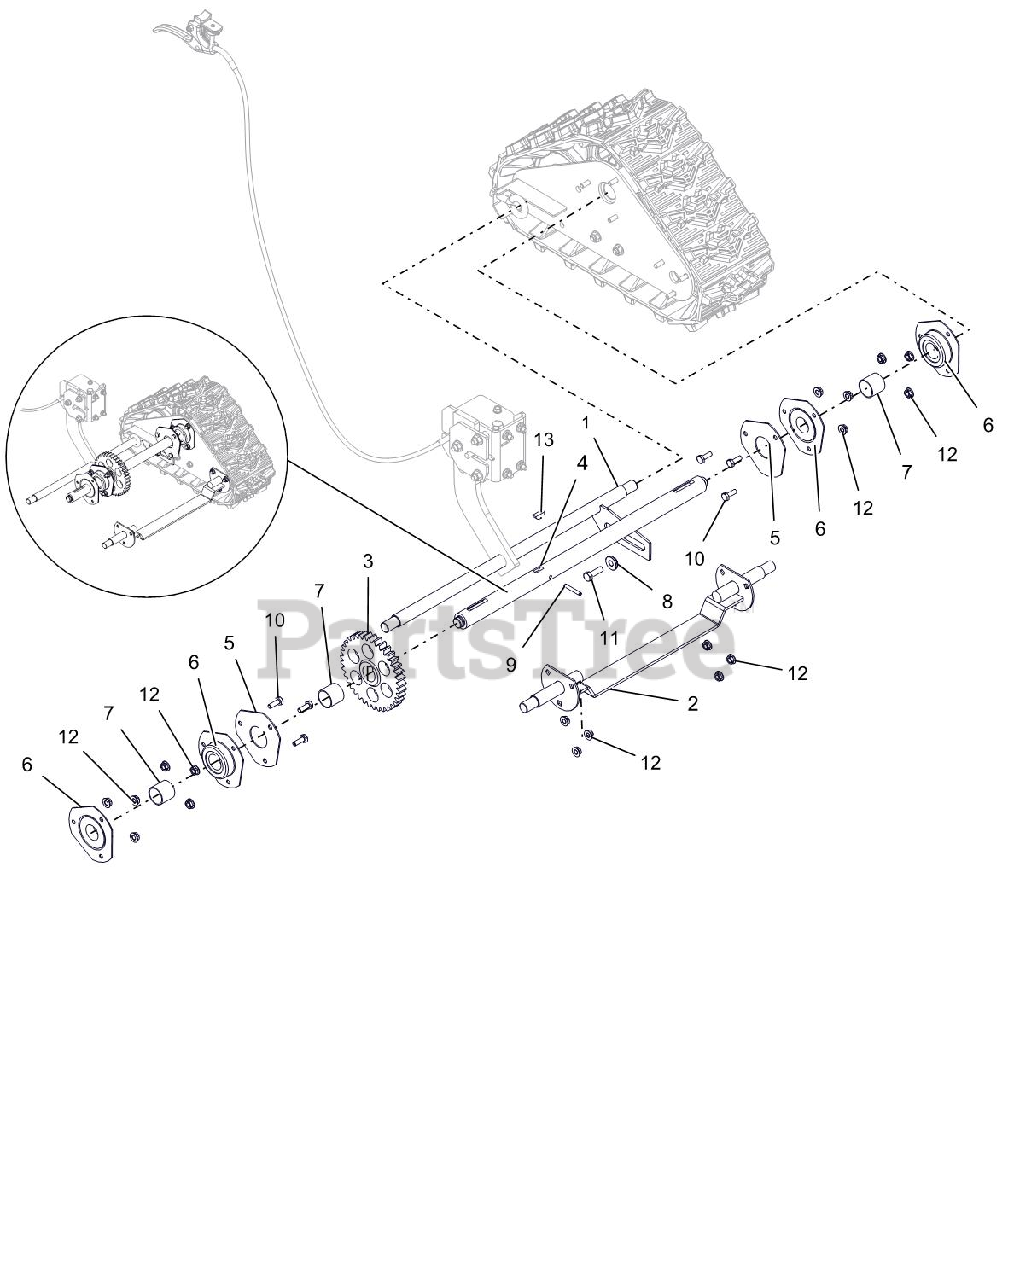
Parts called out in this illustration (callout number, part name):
1	AXLE, REAR - DELUXE TRACK
2	AXLE, FRONT-COMPACT TRACK
3	GEAR, SPUR
4	AXLE, TRACK-DELUXE
5	PLATE, BEARING SPACER
6	BRG-FLG 1.003/1.000 3 BOLT
7	BSHG-SLV, 1.012X1.125X1.00
8	BSHG-FLG .325X.499X.3X.875
9	PIN-ROLL .188X1.25
10	@BLT-HEX .25-20X.75 GR5 YWZC
11	@BLT-HEX .31-18X1.00 GR5 YWZC
12	@NUT-LK-CTR-FLG .25-20 YWZC
13	KEY-WDRF .25X.750X.313 SAE91
